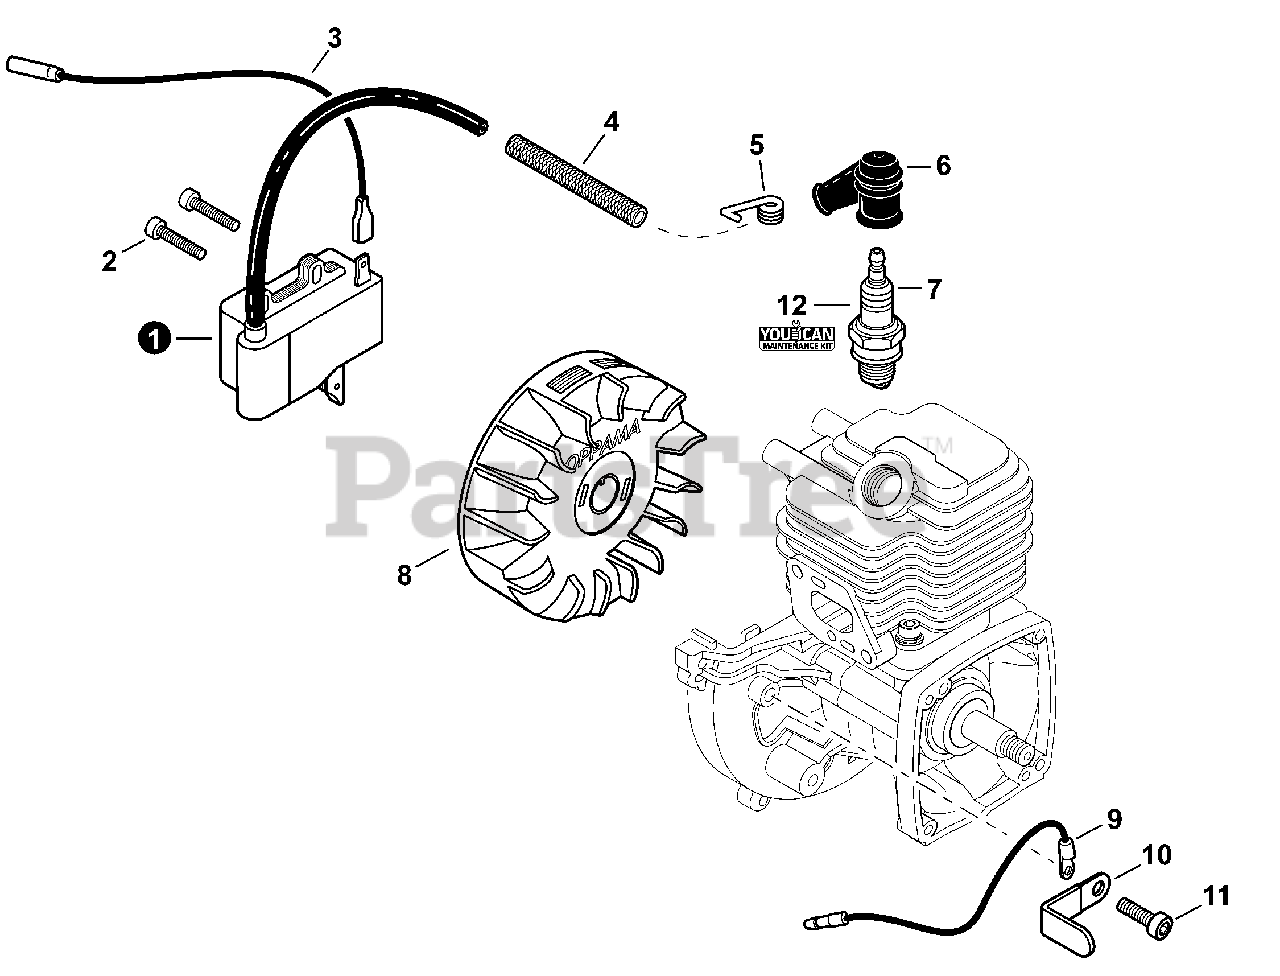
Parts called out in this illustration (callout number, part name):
1	COIL, IGNITION
2	BOLT, TORX 4x20
3	LEAD - IGNITION L= 210
4	TUBE, INSULATOR 8 L= 65
5	TERMINAL, SPARK PLUG
6	CAP, SPARK PLUG
7	SPARK PLUG - BPMR8Y
8	FLYWHEEL
9	LEAD - GROUND L= 115
11	BOLT, TORX 5x10
12	TUNE-UP KIT - YOUCANT
